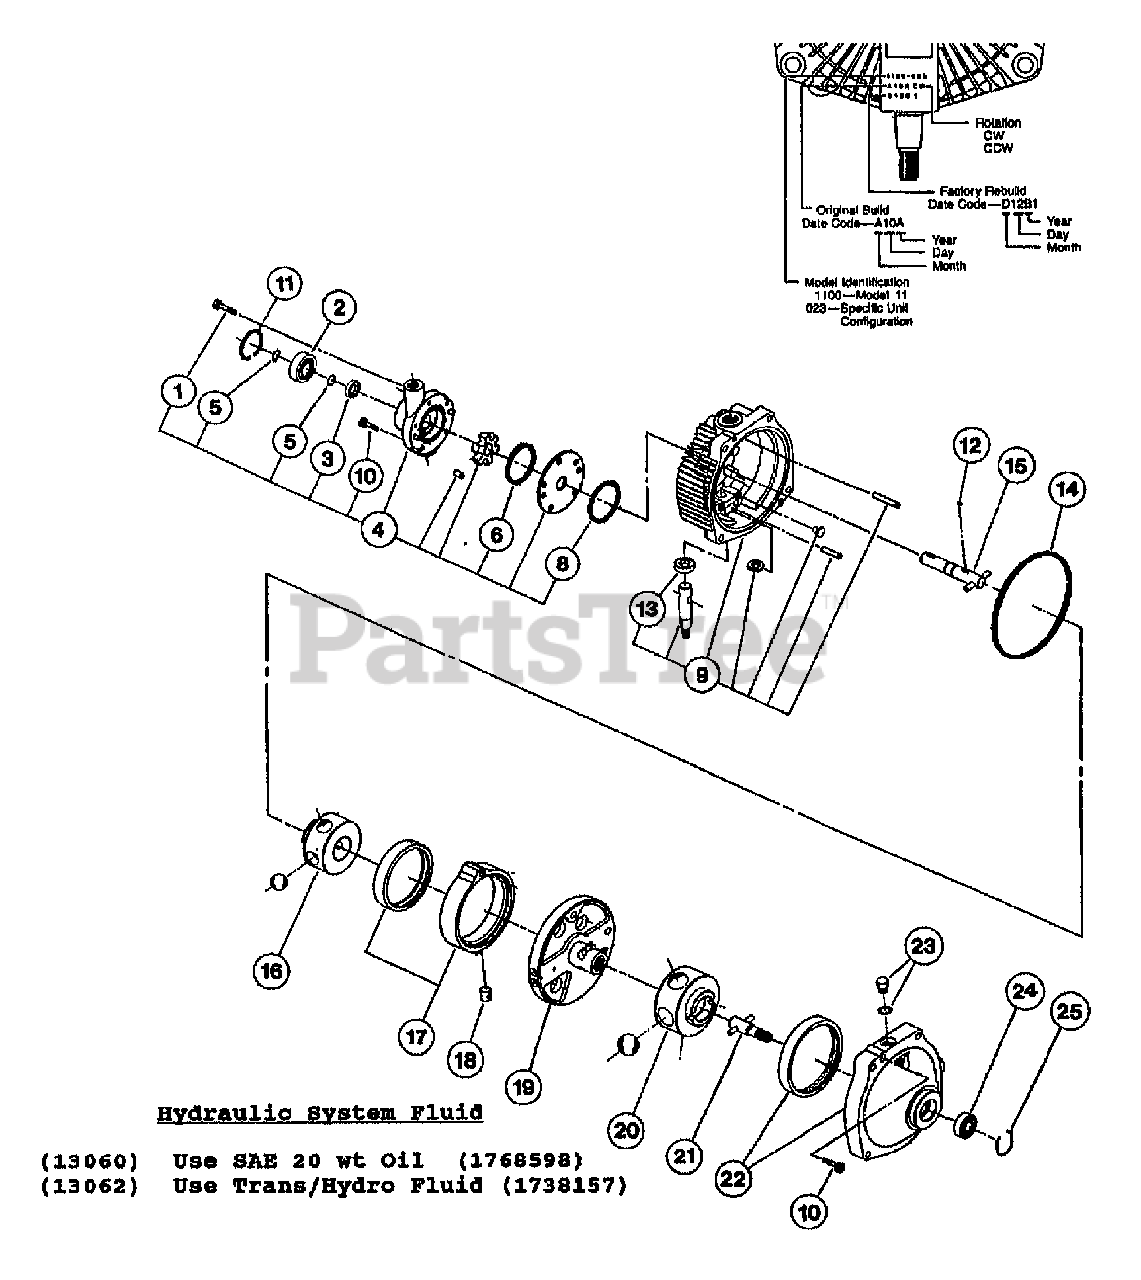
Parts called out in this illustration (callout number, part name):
1	SOCKET HD. CAPSCREW
3	SEAL-OIL
4	KIT-PUMP CHARGE
5	RING-SNAP
6	RING-SQ SEAL
8	RING-SQ SEAL
9	ASSM-COVER
10	SOCKET HD. CAPSCREW
12	PIN-DRIVE
13	SEAL-OIL
14	RING-SQ SEAL
15	SHAFT-INPUT (W/KEY)
16	ASSM-PUMP ROTOR & BALL
17	ASSM-RING CAM
18	RING-CAM INSERT
19	ASSM-PINTLE
20	ASSM-MOTOR ROTOR & BALL
21	SUBASSM-OUTPUT SHAFT
22	ASSM-BODY
23	SUBASSM-O RING PLUG
24	BRG-BALL (OUTPUT)
25	RING-RETAIN
